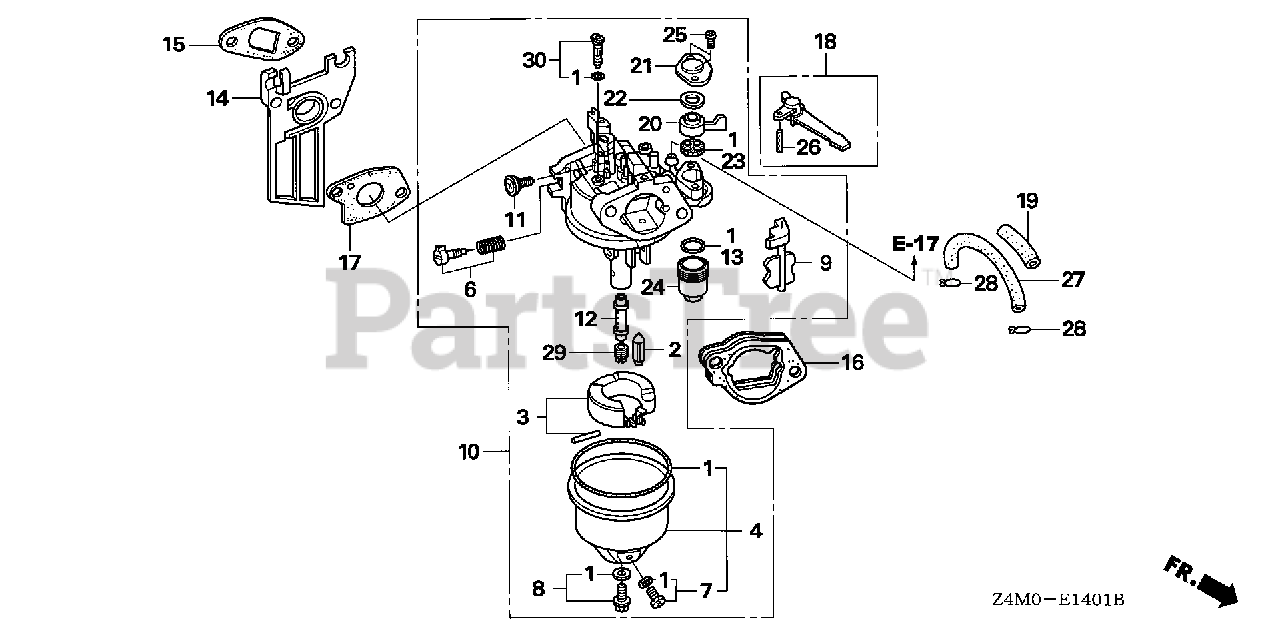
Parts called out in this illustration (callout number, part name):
1	GASKET SET
2	VALVE SET, FLOAT
3	FLOAT SET
4	CHAMBER SET, FLOAT
6	SCREW SET
7	SCREW SET, DRAIN
8	SCREW SET B
9	CHOKE SET
10	CARBURETOR ASSY. (BE65Q A)
11	SCREW, THROTTLE STOP
12	NOZZLE, MAIN
13	GASKET, FUEL STRAINER CUP
14	INSULATOR, CARBURETOR
15	GASKET, INSULATOR
16	SPACER, CARBURETOR
17	GASKET, CARBURETOR
18	LEVER, CHOKE (STD)
20	LEVER, VALVE
21	PLATE, LEVER SETTING
22	SPRING, VALVE LEVER
23	GASKET, VALVE
24	CUP, FUEL STRAINER
25	SCREW, PAN (3X6)
26	PIN, SPRING (2X12)
29	JET, MAIN (#65)
29	JET, MAIN (#68)
29	JET, MAIN (#70)
30	JET SET, PILOT (#35)
